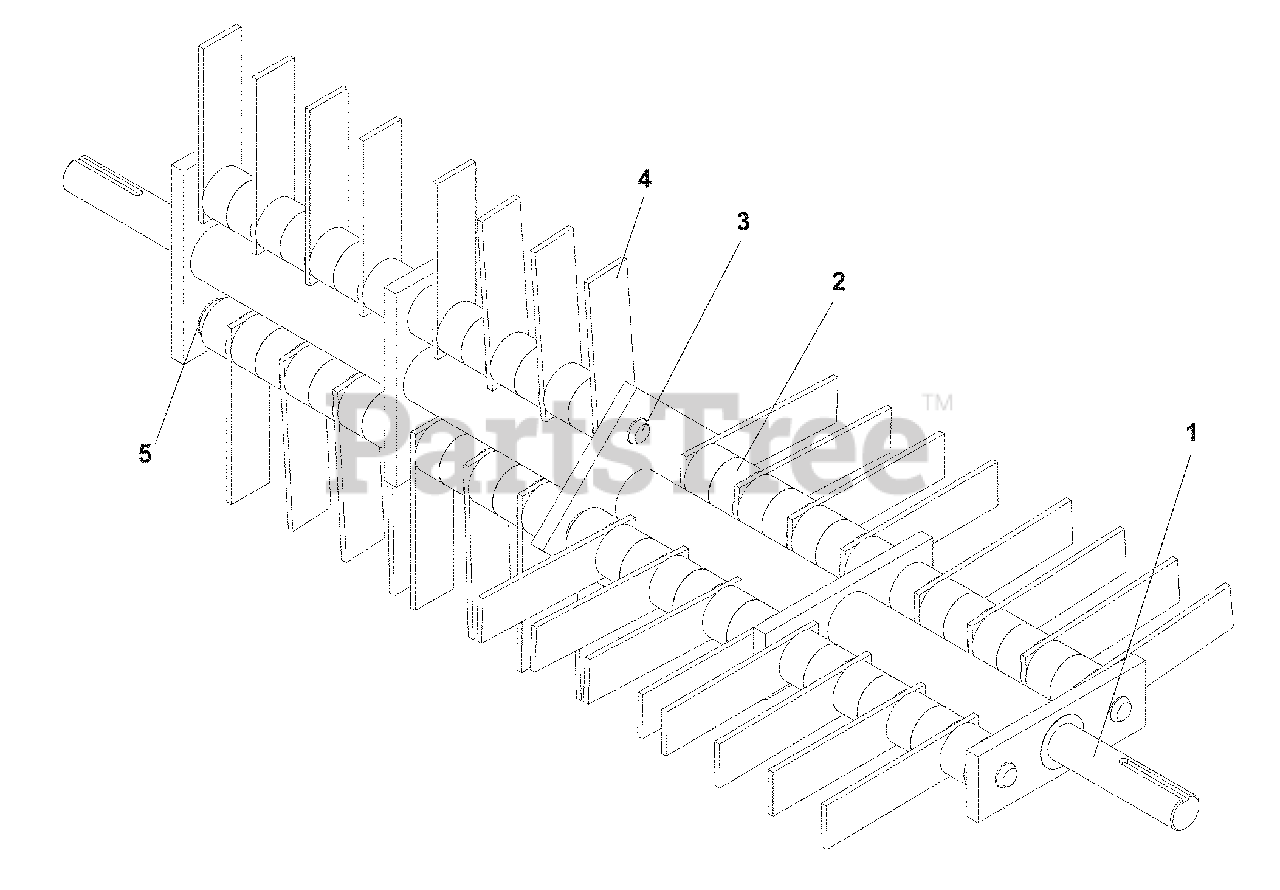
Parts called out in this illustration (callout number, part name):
2	SPACER SET (56 SPACERS)
3	SHAFT & HARDWARE SET(4 SHAFTS)
4	BLADE SET (32 BLADES)
5	E-RING 1/2
